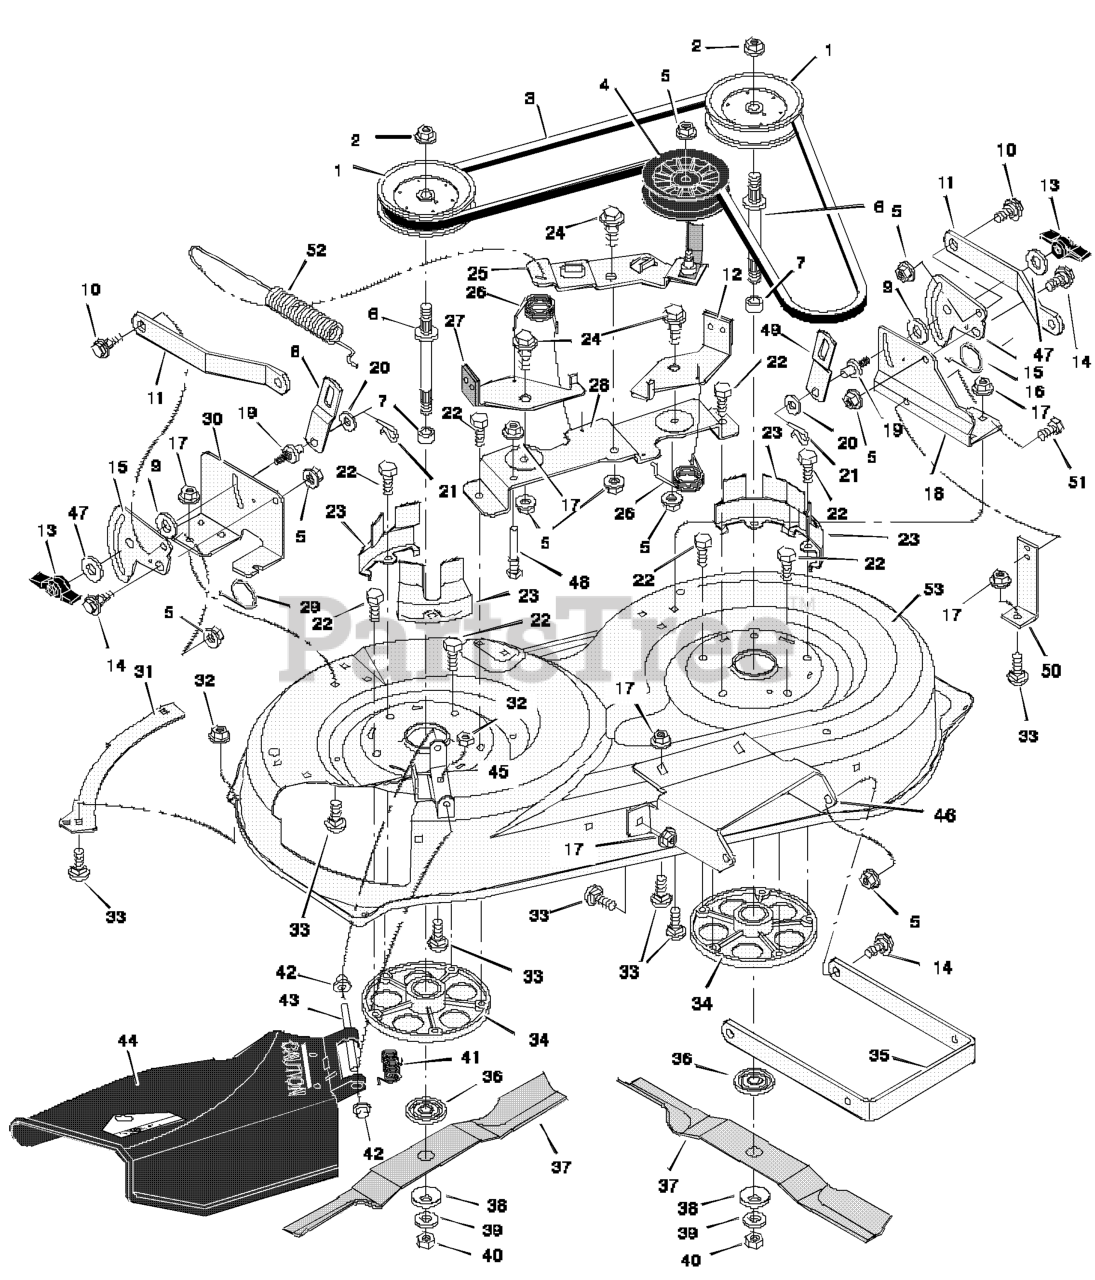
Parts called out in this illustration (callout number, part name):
1	Pulley, Jackshaft
2	Nut, Hex
3	Belt, Mower Drive
4	Pulley, Idler
5	Nut, Flange
6	Jackshaft
8	Link, Right Lift
9	Pad, Friction
10	Bolt, Shoulder
11	Bracket, Suspension
12	Pad Assembly, Left Brake
13	Knob
14	Bolt, Shoulder
15	Plate, Suspension
17	Nut, Flange
18	Bracket, Suspension
19	Pin, Hanger
21	Pin, Cotter
22	Bolt
23	Cover, Pulley
24	Bolt, Shoulder
25	Arm, Idler
26	Spring
27	Pad Assembly, Right Brake
28	Bracket Assembly, Brake
30	Bracket, Suspension
31	Plate
32	Nut, Flange
33	Bolt, Carriage
34	Mandrell
35	Bracket, Suspension
36	Adapter, Blade
41	Spring
42	Cap, Push On
43	Rod, Pivot
44	Deflector
45	Bracket, Deflector
46	Bracket, Front Hanger
48	Guide, Belt
49	Link, Left Lift
50	Bracket, Support
52	Spring, Extension
53	Housing, Blade
